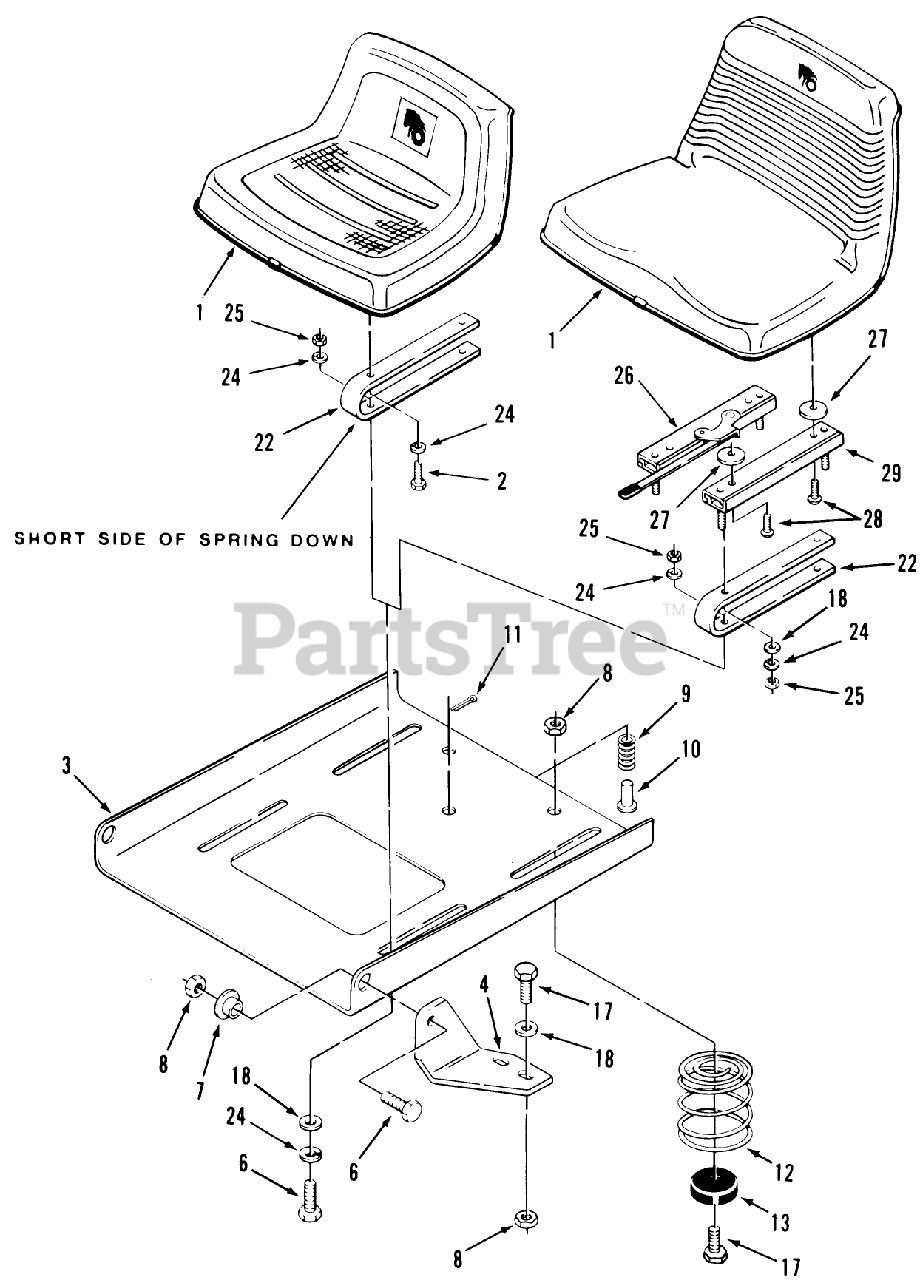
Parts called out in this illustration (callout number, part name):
4	BRACKET-PIVOT L.H *B
4	BRACKET-PIVOT R.H *B (NS)
7	BUSHING
9	SPRING-SEAT SWITCH
12	SPRING-SEAT NYLON
13	BUMPER
18	WASHER 5/16 SAE
27	SPACER-NYLON
